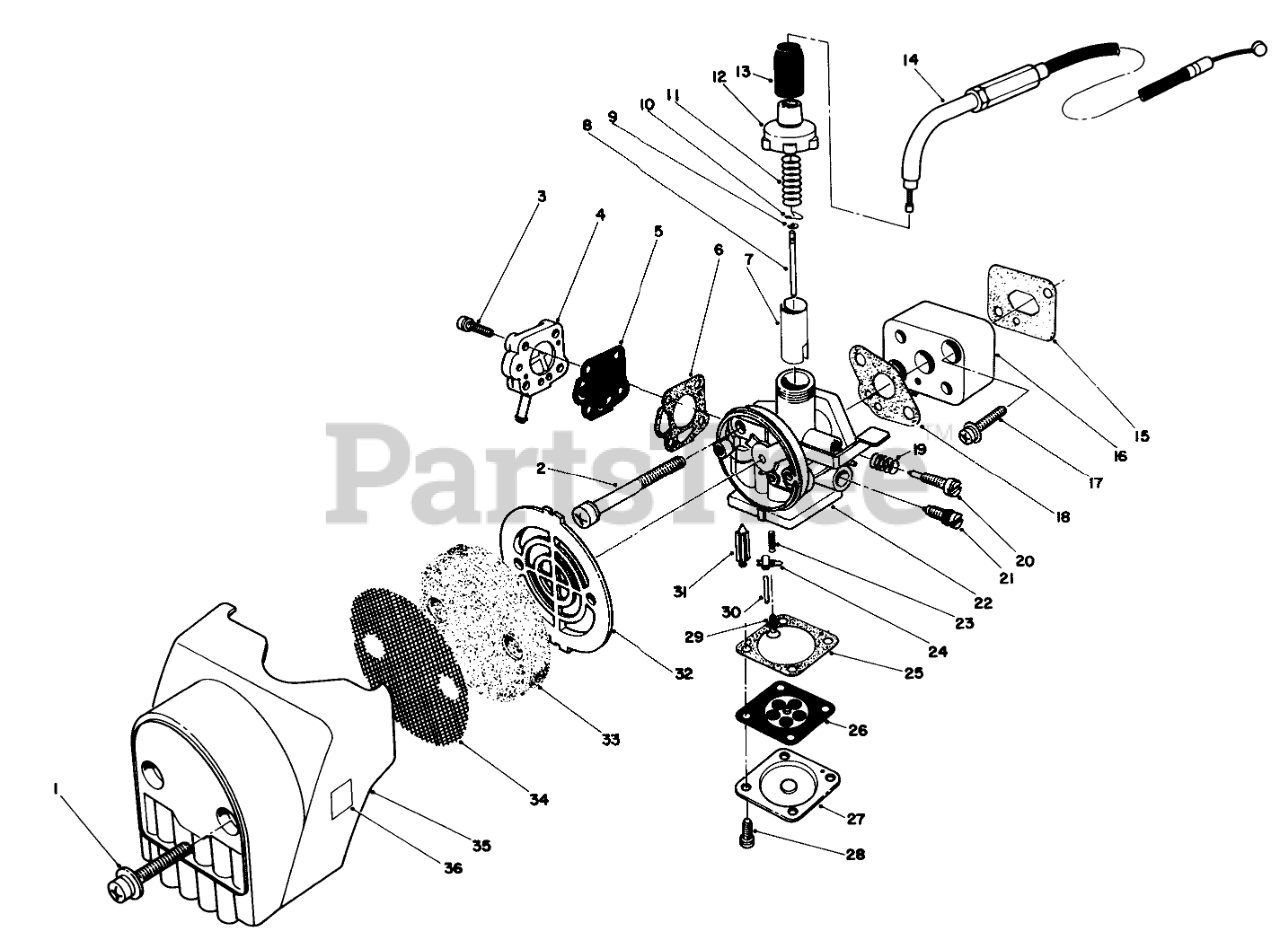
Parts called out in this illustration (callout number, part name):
1	Screw
2	SCREW W/ WASHER
3	SCREW W/ WASHER
4	Cover-Pump
5	Diaphragm-Pump
6	PUMP COVER GASKET
7	VALVE, THROTTLE
8	NEEDLE JET
9	Retainer
11	SPRING
13	AIR SEAL
14	WIRE, THROTTLE
15	GASKET,INSULATOR
16	INSULATOR
17	Screw & Washer
18	CARB. GASKET
19	ADJ. SCREW SPRING
20	SCREW
21	Needle-Main Jet
22	Carburetor Assembly (Incl. Ref. #3-13, 19-21, & 23-31)
23	VALVE SPRING
24	FLOAT ARM
25	DIAPHRAGM GASKET
26	Diaphragm-Main
27	DIAPHRAGM COVER
28	SCREW W/ WASHER
29	FLOAT SCREW
30	FLOAT PIN
31	FLOAT VALVE
33	ELEMENT
34	SCREEN
35	CLEANER COVER
36	CHOKE LABEL
